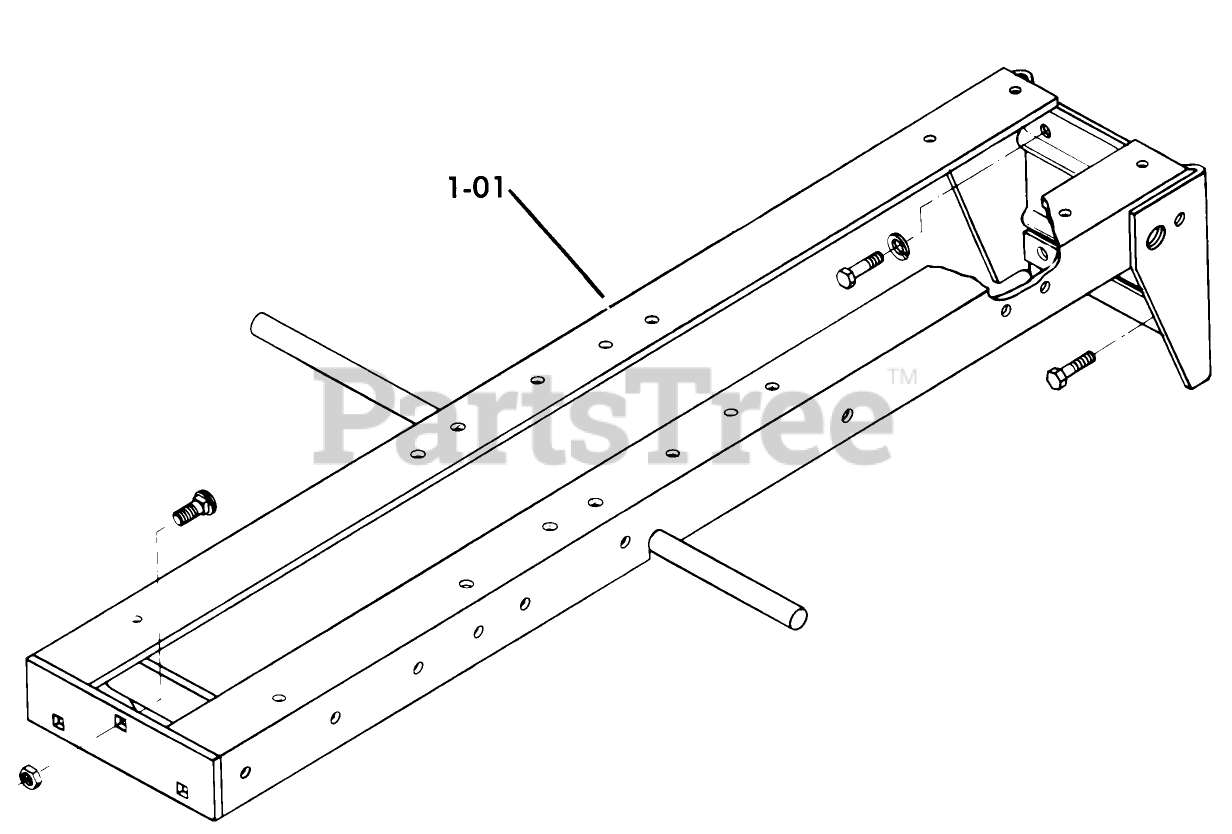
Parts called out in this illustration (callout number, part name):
1-01	Assy-Frame
1-01	Bolt
1-01	LOCKWASHER
1-01	Nut
